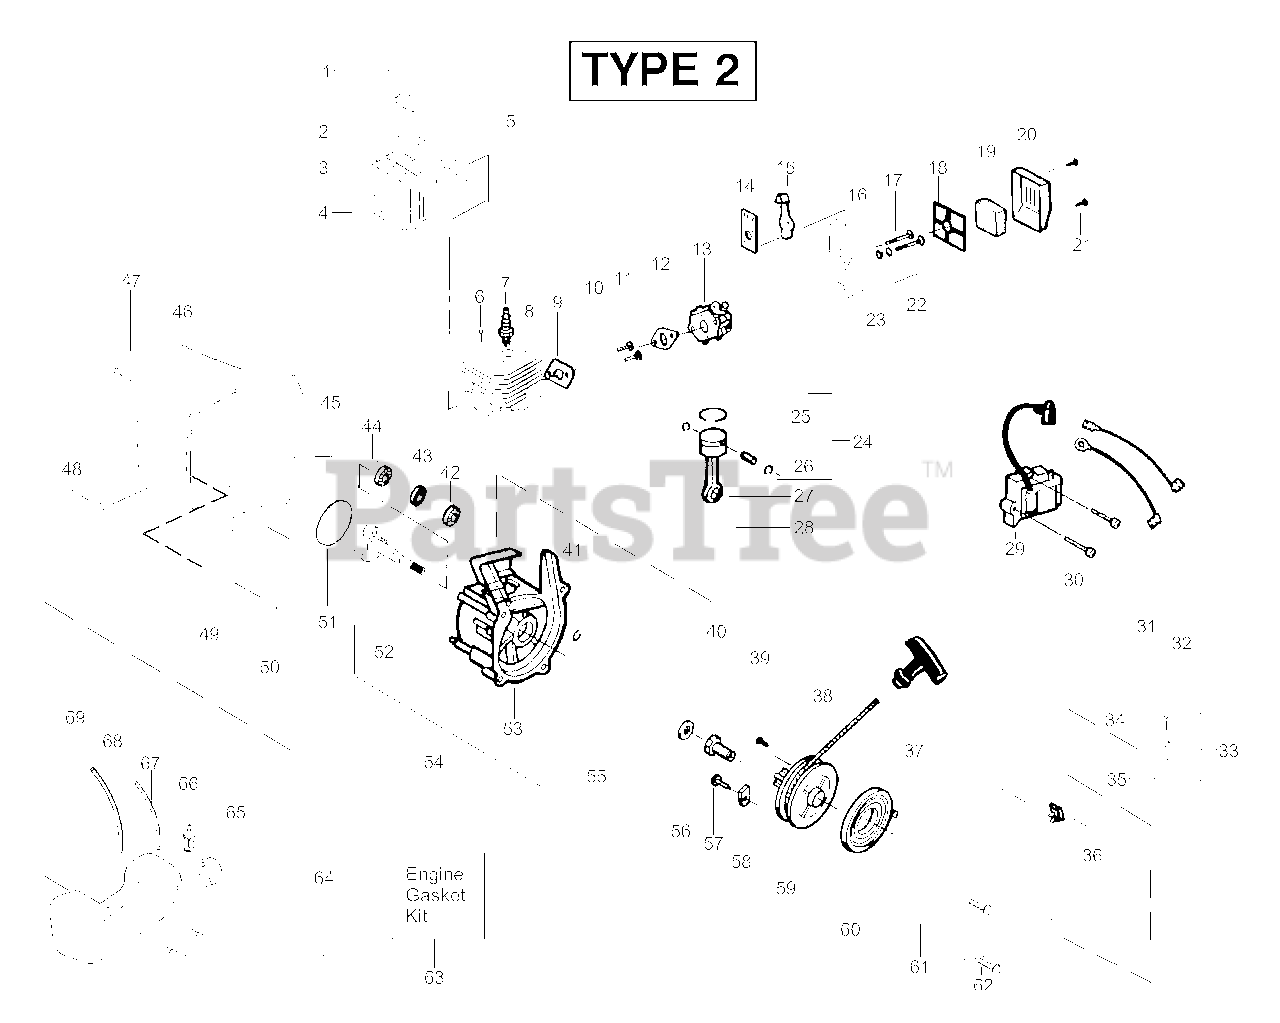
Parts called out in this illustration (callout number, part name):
1	Screw-Screen
2	Kit-Spark Arrestor
3	Kit-Muffler
4	Bolt-Muffler
5	Gasket-Muffler (kit)
6	Screw-Cylinder
7	Spark Plug (RCJ-6Y)
8	Kit - Cylinder
9	Gasket-Cyl./Carb. (kit)
10	Adapter-Carb.
12	Gasket-Carb. (kit)
13	Kit-Carb. (C1Q-W10B)
14	Choke Plate Mounting
15	Shutter-Choke
18	Plate - Filter Support
19	Foam-Air Filter
20	Cover-Air Filter
22	Spacer-Choke
24	Kit - Piston
25	Piston Ring
26	Retainer-Piston Pin
27	Assy-Connecting Rod
28	Seal-Cylinder (kit)
29	Ignition Module
31	Assy-Ground Wire
32	Assy-Leadwire
33	Assy-Nose Cone Clamp
34	Screw-Nose Cone
35	Nut-Nose Cone
36	Kit-Switch
37	Handle-Starter
38	Kit - Rope
40	Coupling-Drive
41	Retain. Ring-C'shaft
42	Outer Bearing
43	Kit-C'case Seal
44	Inner Bearing
45	Shroud-Rear
47	Screw
49	Shield-Heat
50	Screw
51	O-Ring-C'case (kit)
52	Assy-Crankshaft
53	Assy-Crankcase
54	Assy-C'case & C'shaft
55	Assy-Flywheel
56	Washer-Flat
58	Retainer-Can
59	Kit-Starter Pulley
60	Spring-Starter
61	Assy.-Fan Hsg
62	Screw
63	Kit-Engine Gasket
65	Assy-Fuel Cap
66	Assy-Fuel Pickup
67	Kit-Fuel Line (Small)
68	Kit-Fuel Line (Large)
69	Assy-Fuel Tank
